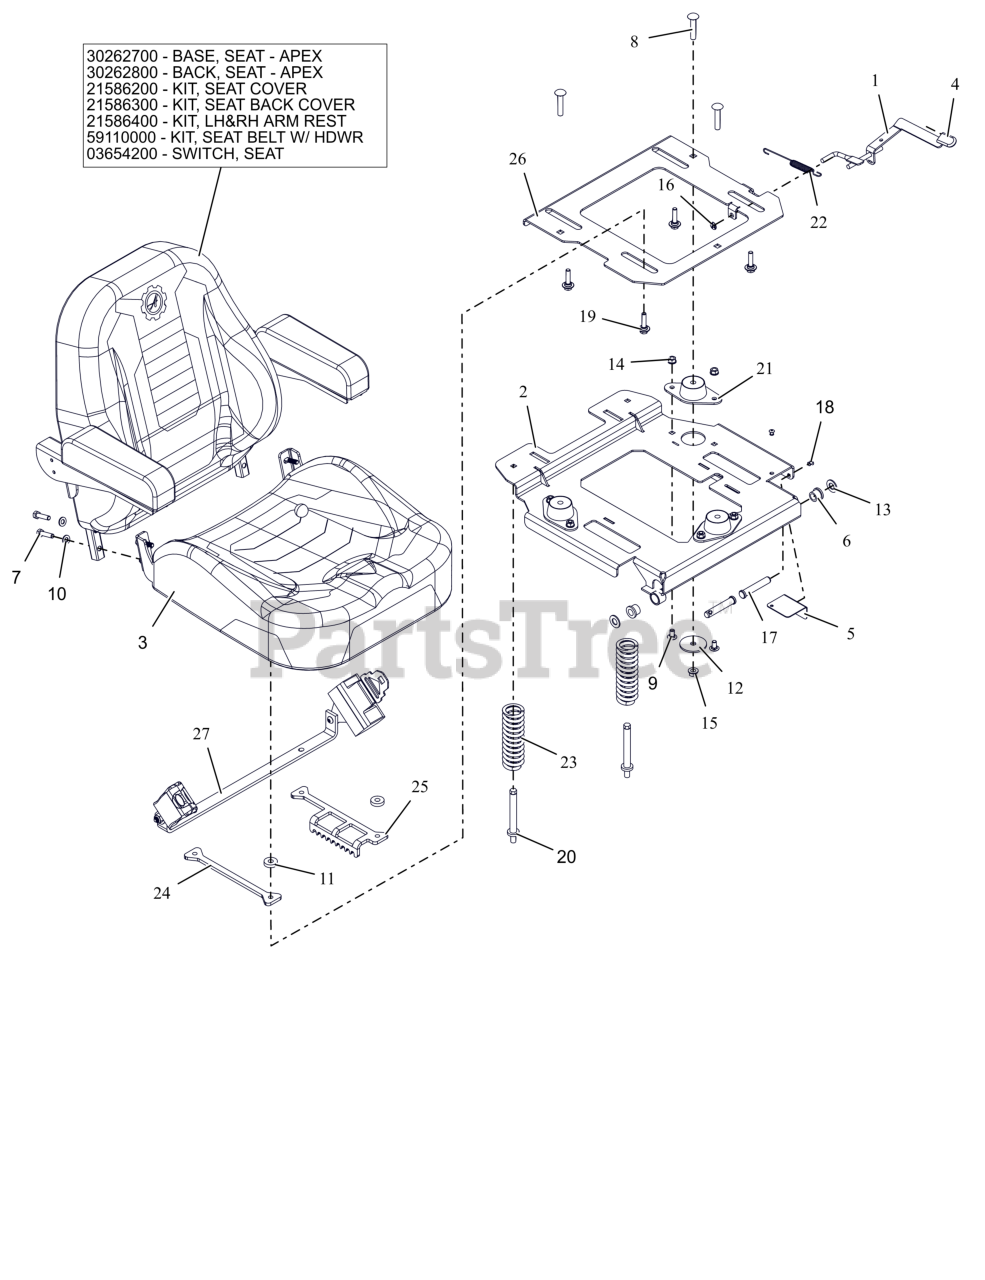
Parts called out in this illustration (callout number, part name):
1	WLDMT, SEAT SLIDE LEVER
2	WLDMT- ISO MTG PLATE 3PT
3	SEAT, ASM APEX/ZENITH
3	BASE, SEAT - APEX
3	BACK, SEAT - APEX
3	KIT, SEAT COVER BOTTOM
3	KIT, SEAT BACK COVER
3	KIT, LH & RH ARM REST
3	KIT-SEAT BELT REPLACE-05007300
3	SWITCH- SEAT
4	GRIP, SEAT LEVER, GREY
5	GUARD, SEAT FAN (SH)(BLACK)
6	BSHG, FLG .516X.750X.625X.937
7	BLT, HEX .31-18X1.25 G5 ZCC
8	BLT,RHSSN.375-16X2.00 G5 ZCC
9	BLT, RHSSN .31-18X.625 G5 ZCC
10	WSHR,FLT .344X.688X.065 ZCC
11	WSHR, FLT .390X1.00X.250 ZCC
12	WSHR-FL-STL 0.406X2X0.125 ZCC
13	WSHR-FL-NYL .518X1.000X.080
14	NUT,LK-CTR-FLG .31-18 GF ZCC
15	NUT-LK-CTR-FLG .375-16 GF ZCC
16	NUT-PUSH .312
17	PIN-CLIC .50X2.70X2.31 -ZCC
18	RVT-POP .187x.250 (#64) BLK
19	BOLT SHLDR .31-18 X .175
20	BOLT, SEAT SPRING
21	MOUNT, FAIL-SAFE COMPRESSION
22	SG-TENS .06X.482X5.35
23	SPRING, COMPRESSION SEAT 224LB
24	PLATE, ADJ SEAT SLIDE (BLACK)
25	PLATE, SEAT ADJ (BLACK)
26	PLATE- SEAT MTG 3PT (ISO KIT)
27	KIT-SEAT BELT REPLACE-05007300
